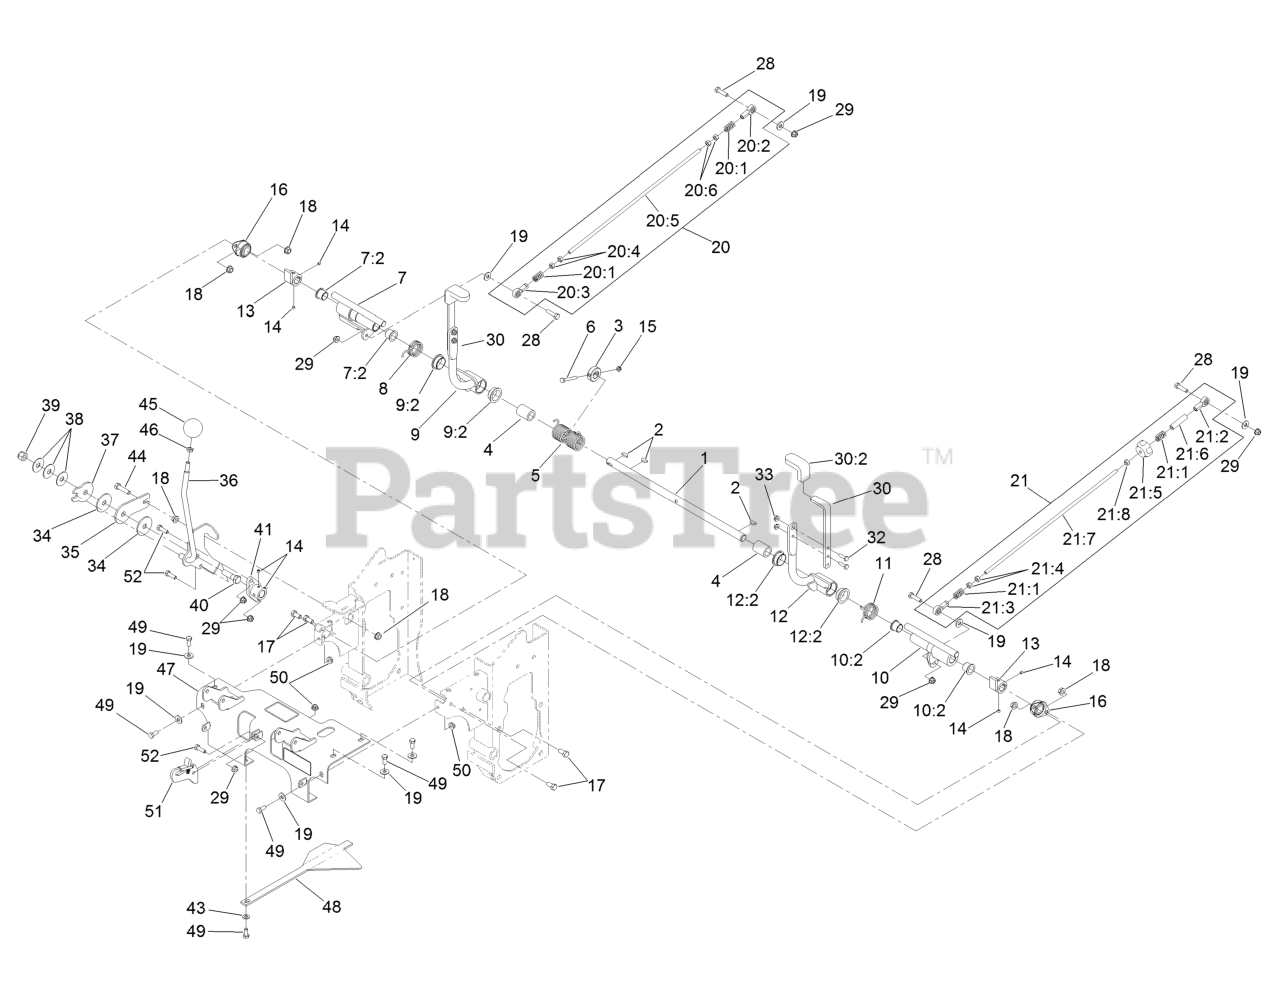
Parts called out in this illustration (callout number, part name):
1	SHAFT-CONTROL, SPEED
2	KEY-WOODRUFF
3	STOP-HUB, CENTER
4	BUSHING-PLASTIC
5	SPRING-TORSION, DOUBLE
6	SCREW-HH
7	RH CONTROL HUB ASM
7:2	BEARING-FLANGE, IGLIDE
8	SPRING-TORSION, RH
9	RH STEERING HANDLE ASM
9:2	BEARING-FLANGE, IGLIDE
10	LH CONTROL HUB ASM
10:2	BEARING-FLANGE, IGLIDE
11	SPRING-TORSION, LH
12	LH STEERING HANDLE ASM
12:2	BEARING-FLANGE, IGLIDE
13	HUB-SPEED CONTROL
14	SCREW-SET
15	NUT-LOCK, NI
16	BEARING-FLANGE, SIDE
17	SCREW-HH
18	NUT-HHF, WHIZ
19	WASHER-FLAT
20	RH PUMP LINKAGE ASM
20:1	SPRING-COMPRESSION
20:2	BALLJOINT-RH
20:3	BALLJOINT-LH
20:5	ROD-LINKAGE, STEERING
20:6	NUT-HEX
21	LH PUMP LINKAGE ASM
21:1	SPRING-COMPRESSION
21:2	BALLJOINT-RH
21:3	BALLJOINT-LH
21:5	KNOB-TRACKING
21:7	ROD-LINKAGE, STEERING
21:8	NUT-HEX
28	SCREW-HH
29	NUT-HF, NI
30	HANDLE ASM
30:2	GRIP-HANDLE, STEERING
32	SCREW-HH
34	DISC-FRICTION
35	PLATE-FRICTION, SPEED CON
36	LEVER-SPEED CONTROL
37	PLATE-FRICTION, SPEED CON
38	WASHER-DISC, SPRING
39	NUT-HEX
40	SCREW-HH
41	HUB-CONTROL, SPEED
43	WASHER-PLAIN
44	SCREW-HH
45	KNOB-BALL, SPEED CONTROL
46	NUT-JAM
47	CONSOLE ASM
48	GUIDE-PLENUM
49	SCREW-HH
52	SCREW-HH
